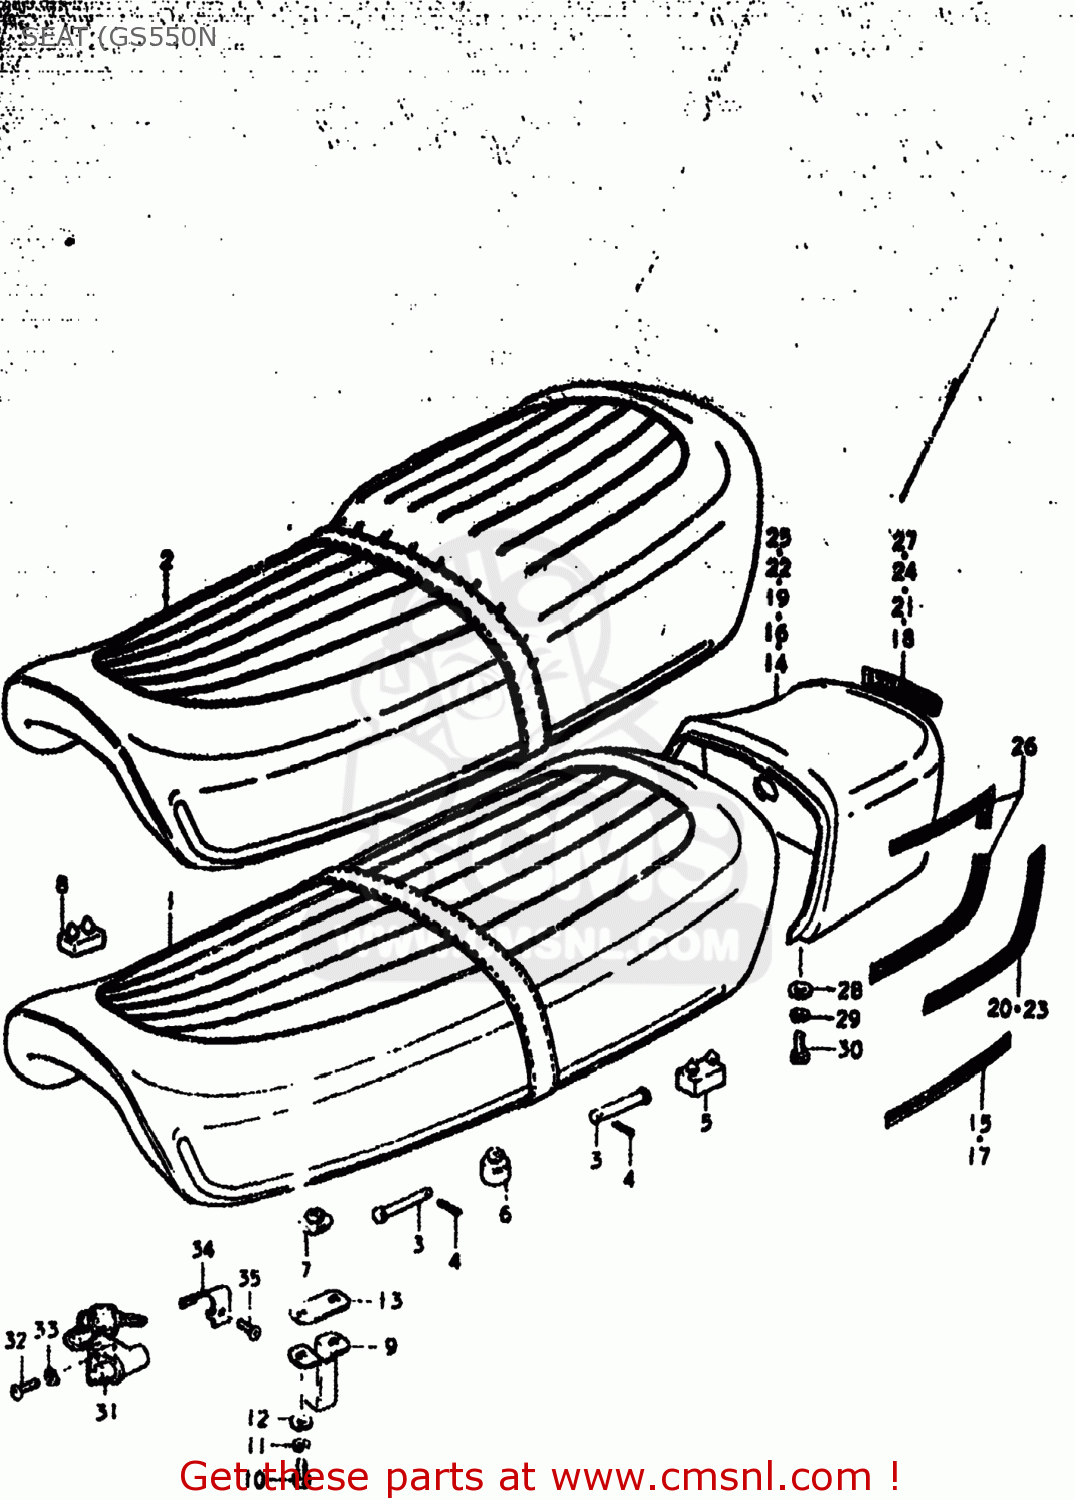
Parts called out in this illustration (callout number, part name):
1	SEAT ASSEMBLY
2	SEAT ASSEMBLY
3	PIN
4	PIN
5	CUSHION
6	CUSHION(11.5X22X20)
7	CUSHION
8	CUSHION
9	STRIKER,SEAT LOCK
10	BOLT
11	LOCK WASHER
12	WASHER 6MM
13	WASHER(8.5X18X1)
14	COVER,SEAT TAIL
17	WASHER
18	NUT 6MM
19	EMBLEM
20	LOCK ASSY,SEAT
21	SCREW
22	LOCK WASHER
23	SPRING,HELMET HOLDER
24	BOLT 5X16
